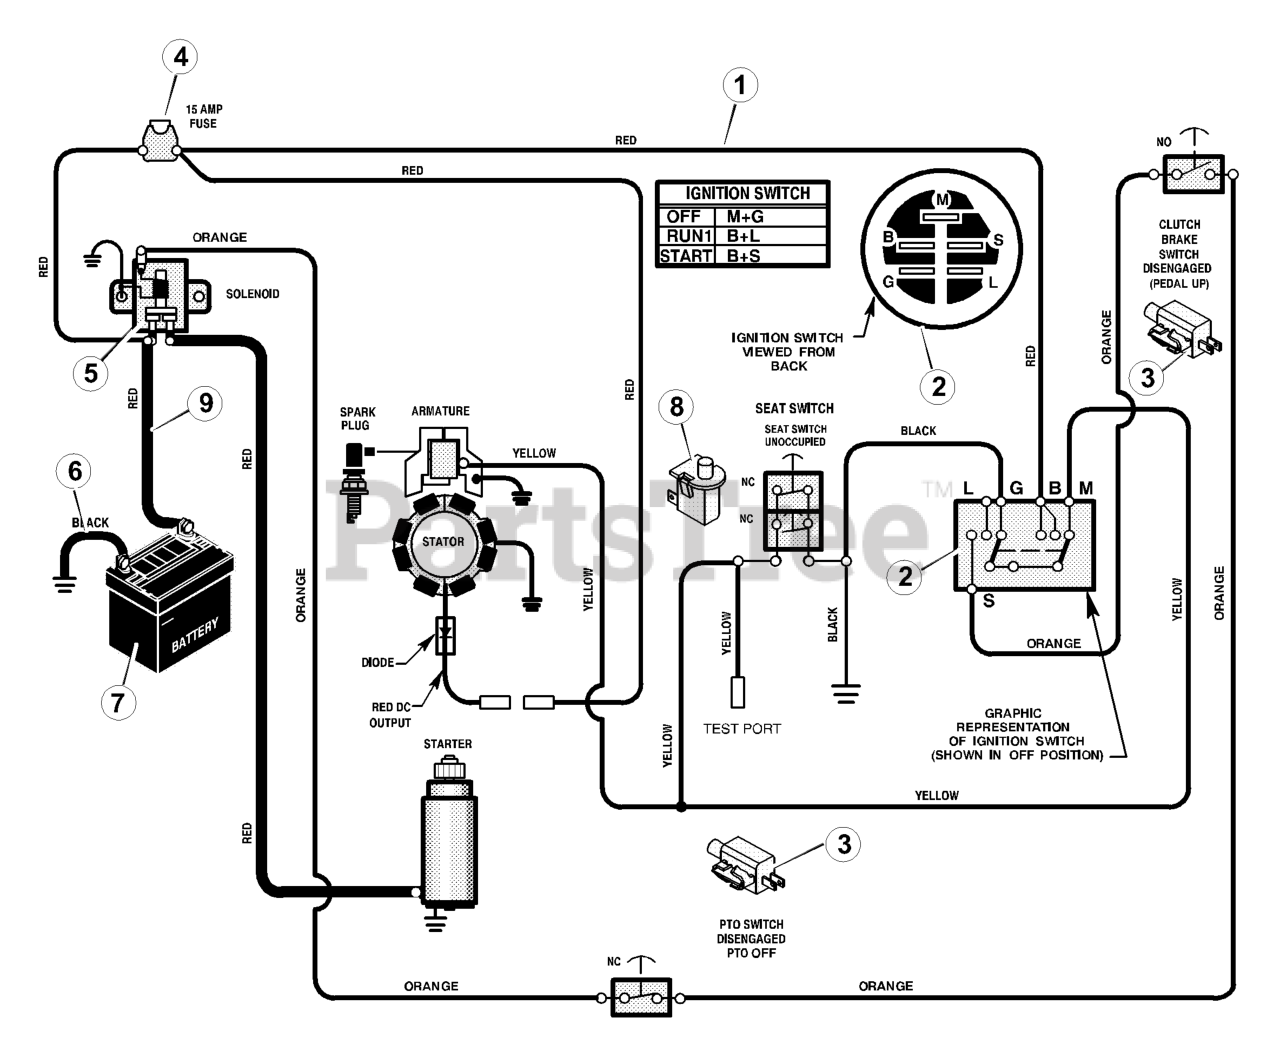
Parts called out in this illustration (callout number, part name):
1	Harness, Chassis Wire
2	Switch, Ignition
3	Switch, Limit
5	Solenoid
6	Cable, Battery Ground
7	Battery
8	Switch, Seat Sensor
9	Cable, Red Battery
